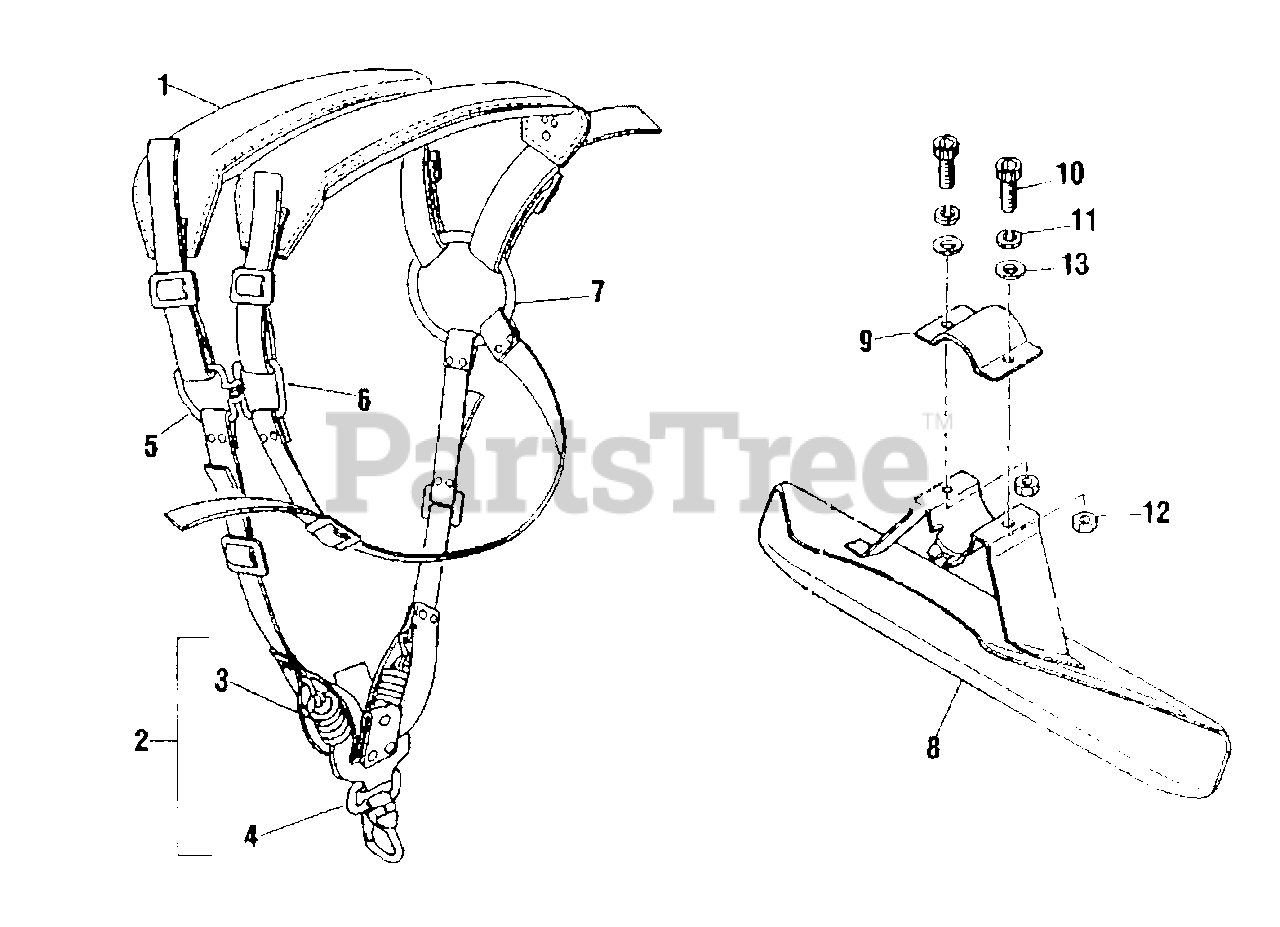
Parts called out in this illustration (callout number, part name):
1	PROTECTOR
2	HOLDER
3	SPRING
4	HOOK
5	CHEST LATCH (A)
6	CHEST LATCH (B)
7	RING
8	GUARD
9	GUARD, CLAMP
10	SCREW - 5X16
11	LOCKWASHER - 5
13	WASHER - 5
